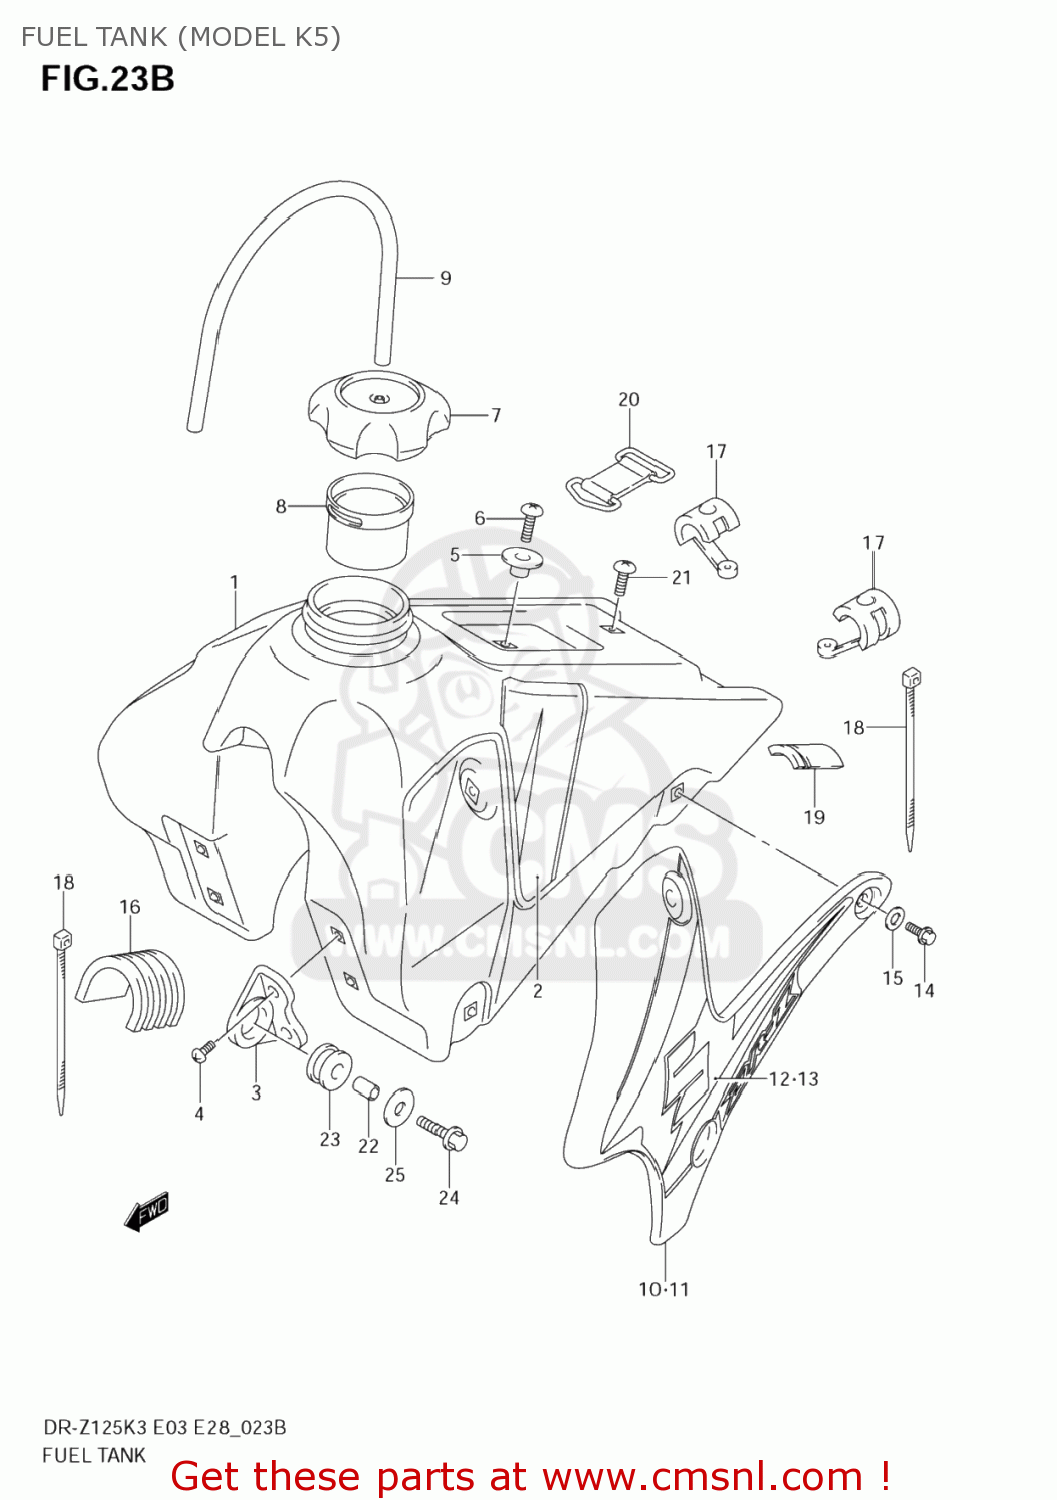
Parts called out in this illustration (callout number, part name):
1	TANK ASSY,FUEL(BLACK)
2	TAPE SET,FUEL TANK
3	BRACKET,FUEL TANK FR
4	BOLT
5	HOOK,SEAT FR
6	SCREW
7	CAP ASSY,FUEL TANK FILLER
8	TUBE,FILLER INLET
9	HOSE(5X8.2X600)
10	COVER,FUEL TANK,R
11	COVER,FUEL TANK,L
12	TAPE,FUEL TANK COVER,R
13	TAPE, FRONT COVER LH
14	BOLT
15	WASHER
16	CUSHION,FUEL TANK
17	CUSHION,FUEL TANK SIDE
18	CLAMP(L:300)
19	CUSHION,FUEL TANK RR
20	BAND,FUEL TANK RR
21	SCREW
22	SPACER(6.5X9X13.5)
23	CUSHION,FUEL TANK FR
24	SCREW
25	WASHER(6.5X24X1.2)
